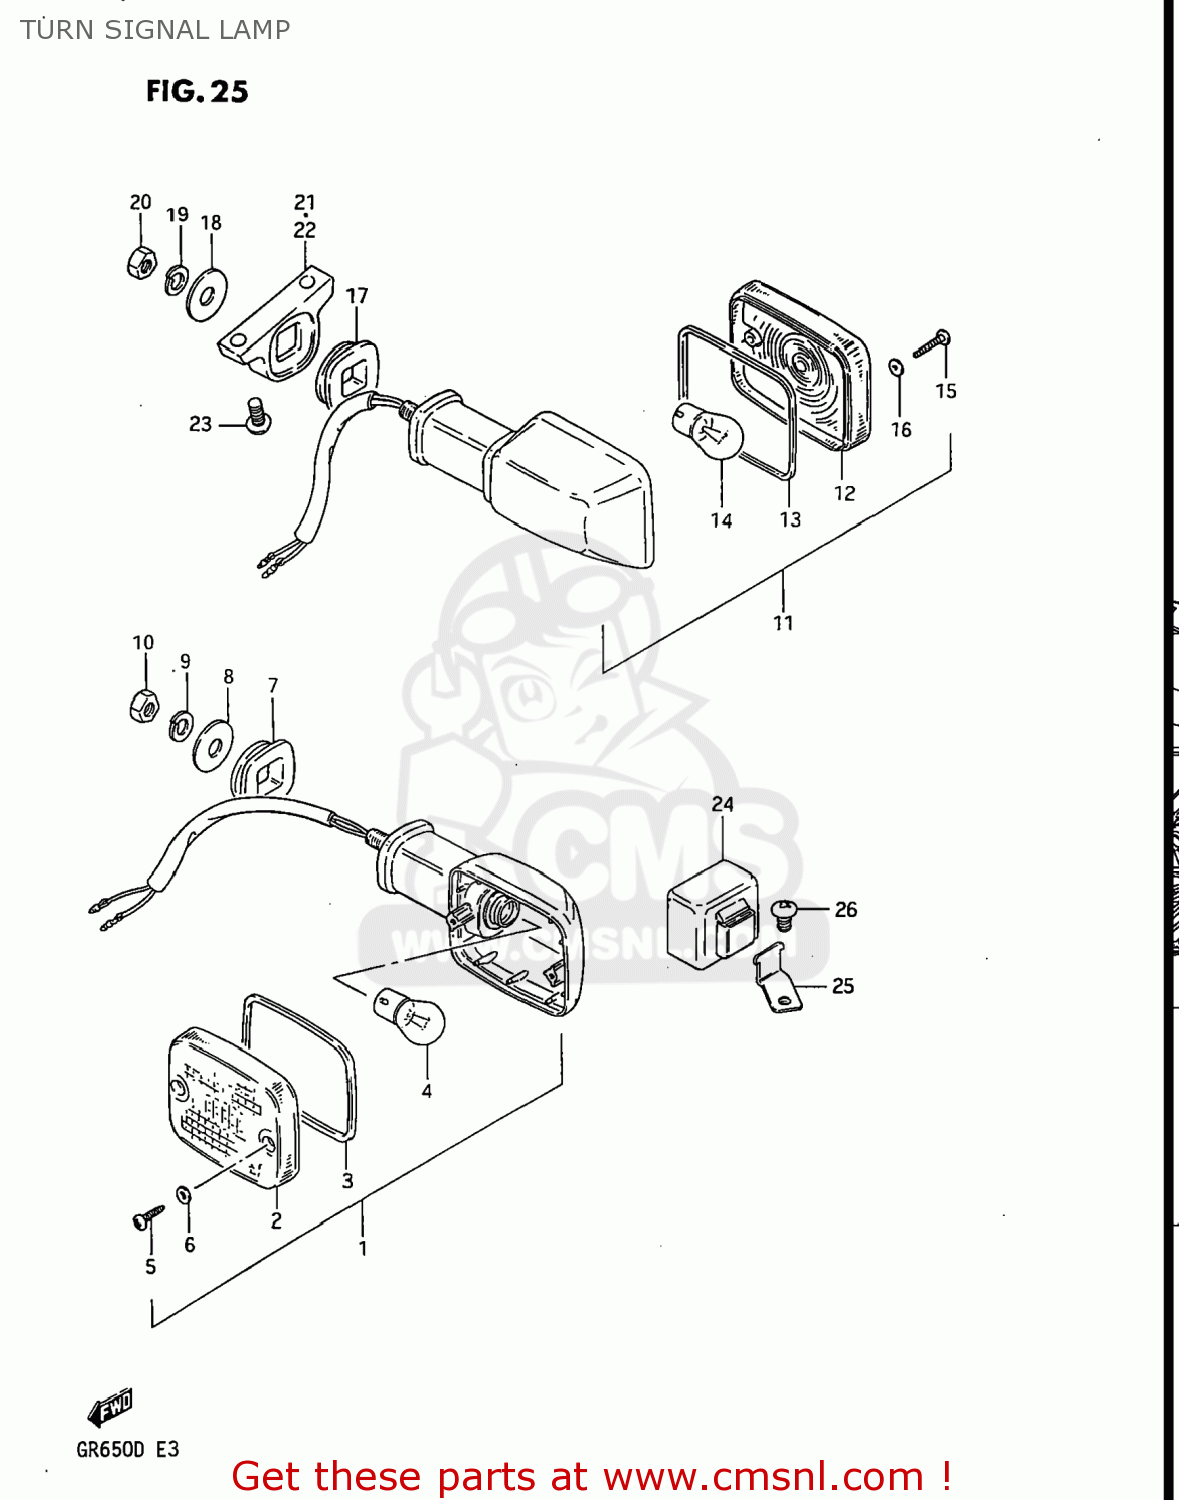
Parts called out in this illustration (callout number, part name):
1	LAMP ASSEMBLY,FRONT TURN SIGNAL
2	LENS
3	GASKET (NAS)
4	BULB(12V23W,STANLEY,A4577A)
5	SCREW
6	GASKET (NAS)
7	CUSHION
8	WASHER (10.5X30X2.3)
9	LOCK WASHER
10	NUT
11	LAMP ASSEMBLY,REAR TURN SIGNAL
12	LENS
13	GASKET (NAS)
14	BULB(12V23W,STANLEY,A4577A)
15	SCREW
16	GASKET (NAS)
17	CUSHION
18	WASHER (10.5X30X2.3)
19	LOCK WASHER
20	NUT
21	BRACKET,REAR TURN SIGNAL
22	BRACKET,REAR TURN SIGNAL
23	SCREW
24	RELAY,TURN SIGNAL
25	BRACKET,TURN SIGNAL RELAY
26	SCREW
